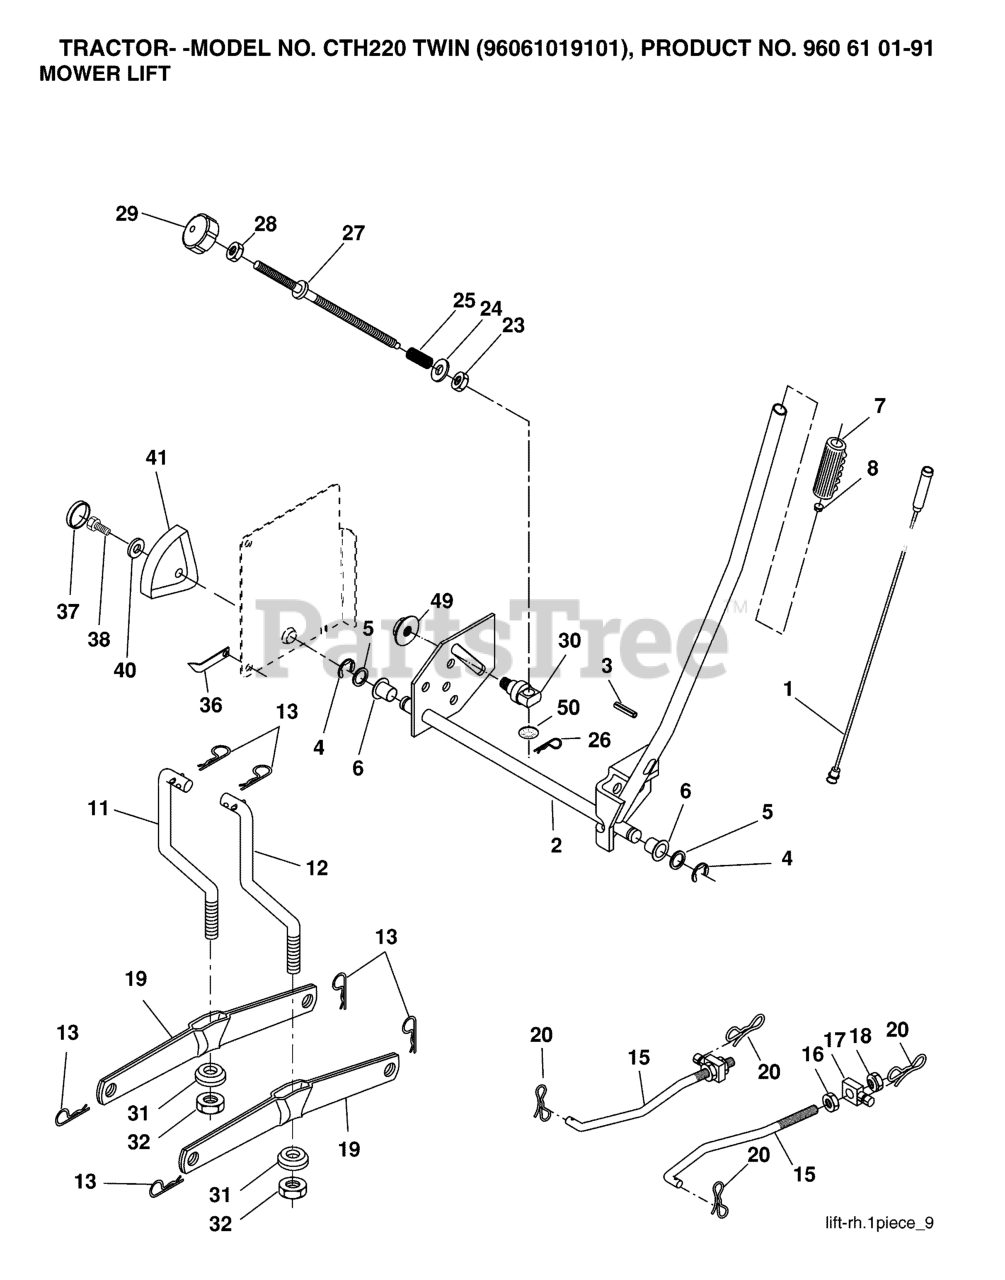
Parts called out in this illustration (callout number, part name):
2	SHAFT.ASM.LIFT.YT
3	PIN.GROOVE.5/16
4	RETAINING RING LT
6	BEARING.NYLON
7	GRIP HANDLE
8	REPL BY 532 12 59-25
11	LINK
12	LINK
13	RETAINER-SPRNG RB
15	LINK.SUSPENSION.FRONT
16	NUT.HEX.JAM.1/2-13
18	NUT.LK.W/WSH.1/2.
19	ARM.REAR.SUSPENSION
20	PIN.COTTER.7/16.BOW TI.
26	RETAINER CLIP
27	ROD ADJ LIFT
28	NUT
29	KNOB INF 3/8-16
31	BEARING.PIVOT.LIFT
32	NUT CROWNLOCK 3/8-24
36	POINTER, HEIGHT INDICATOR(2 2)
38	SCREW 5/16-18X1
41	HEIGHT INDICATOR
49	NUT
50	NUT PUSH M
